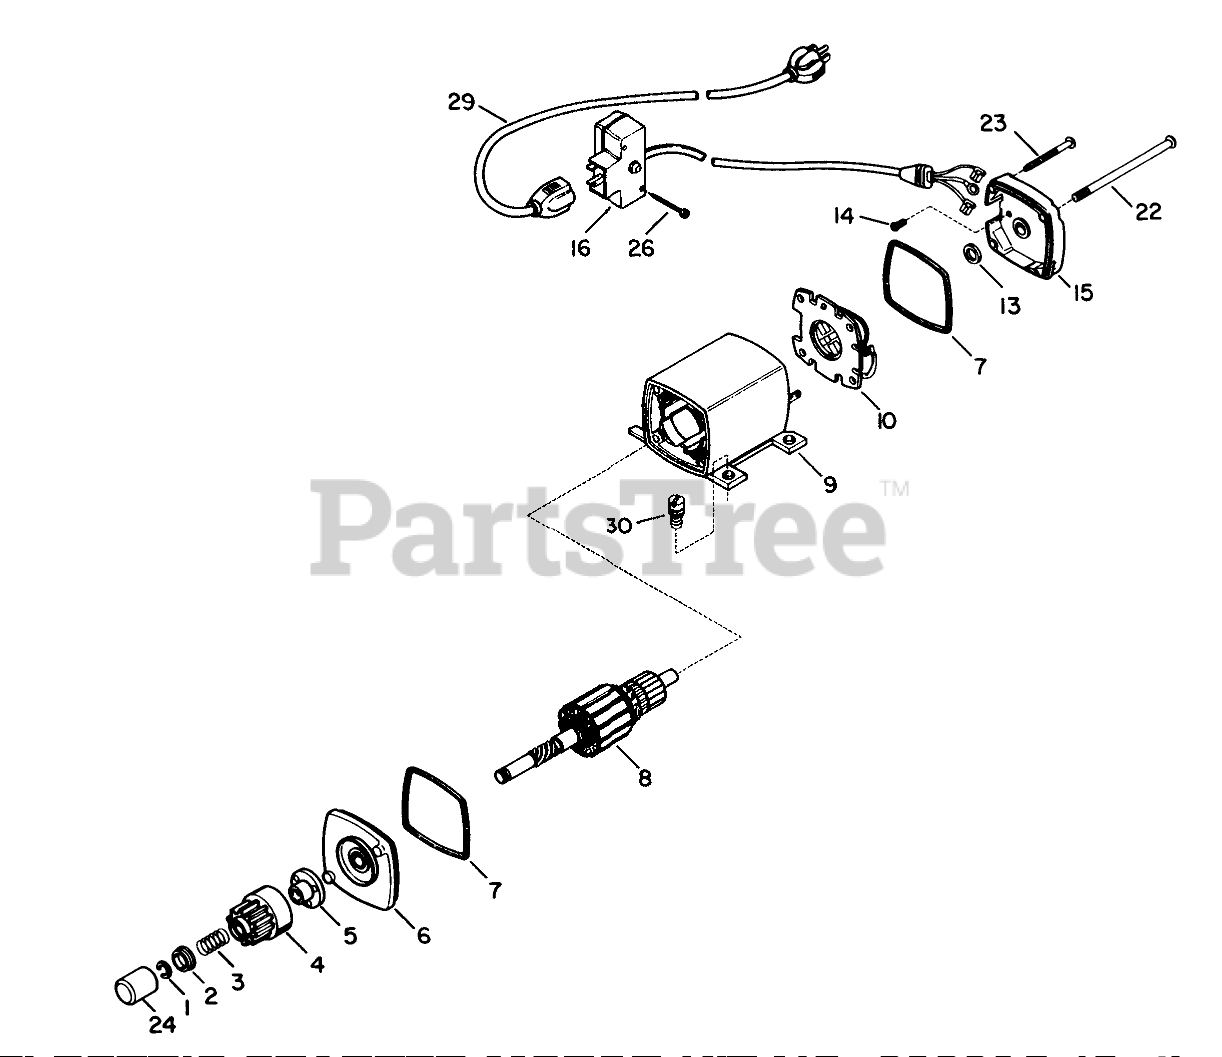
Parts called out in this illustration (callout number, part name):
1	Ring-Retainer
2	Retainer-Spring
3	Spring-Anti Drift
5	Nut-Engaging
6	Drive End Cap Assembly (Incl. Ref. #7)
8	Armature
9	Housing ASM
10	Card ASM
13	Washer-Thrust
14	Screw-Ground
15	Commutator End Cap Assy. (Incl. Ref. #7)
16	Switch Box ASM
22	Bolt-Case
23	Screw-Ground
24	Cover-Dust
29	Cord-Extension
